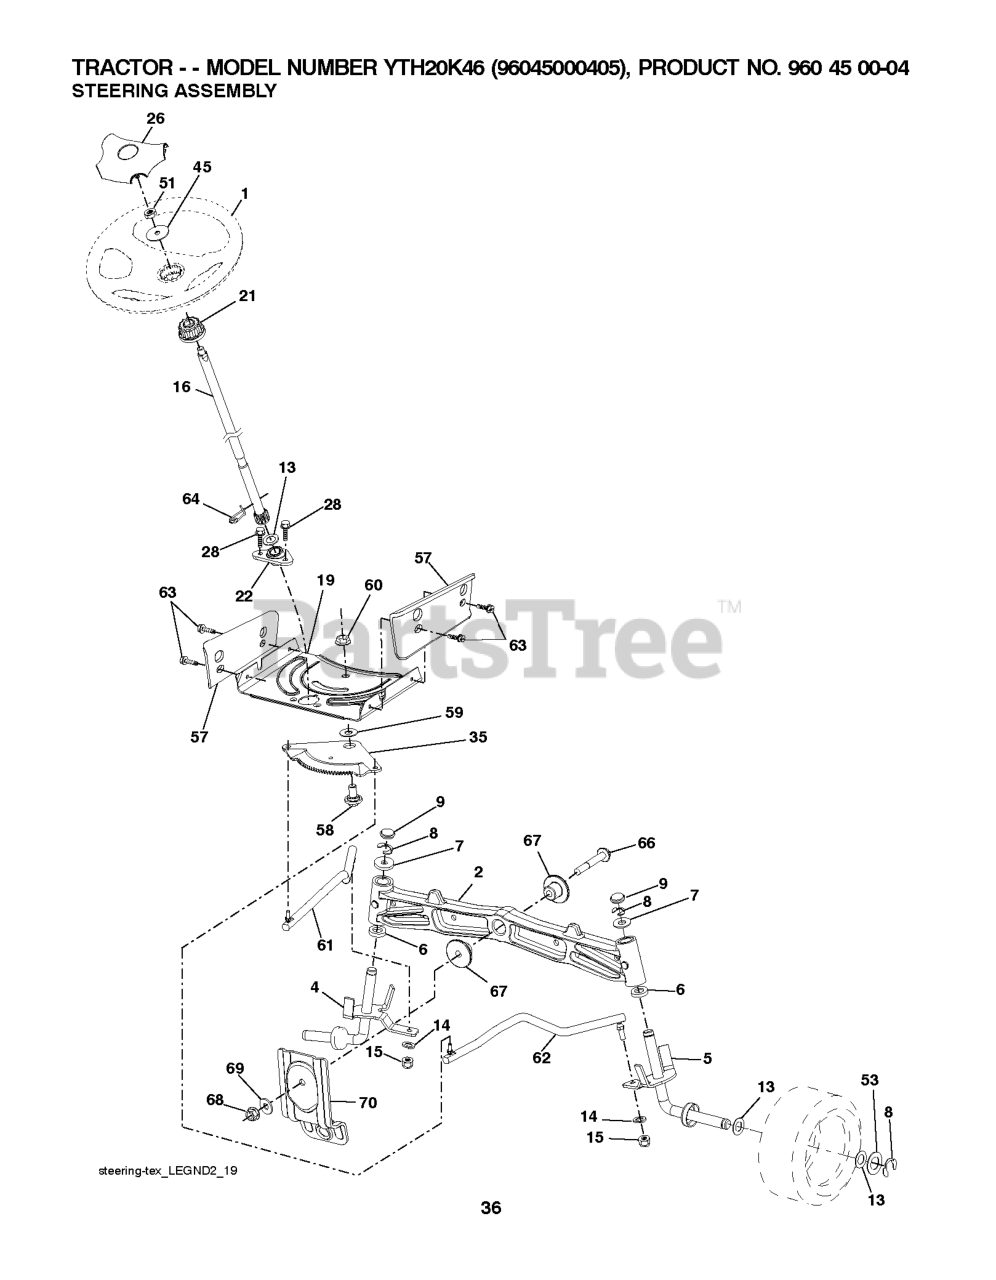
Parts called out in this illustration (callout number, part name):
1	WHEEL.STEERING.LEGEND2.GRY
2	AXLE ASSY FRONT
4	SPINDLE.WELDED.LH.15"TEX
5	SPINDLE.WELDED.RH.15"T
6	THRUST WASHER
9	CAP.SPINDLE.BLACK
14	WASHER, LOCK 3/8
15	NUT CROWNLOCK 3/8-24
16	SHAFT, STEERING
19	PLATE.STEER.DDL.NLT/NG
21	ADAPTER, WHEEL STNG..
22	BUSHING.ASM.STEERING.A
26	INSERT.CAP.STRG.WH.GRAY
28	SCREW, 3/8-16X3/4
35	GEAR.SECTOR.PLATE.DDL.
45	WASHER 9/16"ID, 2 3/8"OD
51	NUT.HEX.1/2-20
53	WASHER.HARDENED
57	BRACKET.UPSTOP.TEX
58	BOLT.SHOULDER.SECTOR.P
59	WASHER.THURST.SECTOR.S
60	NUT FLANGE LOCK 5/8-11
61	DRAGLINK.LH.BALLSTUD.D
62	DRAGLINK.RH.BALLSTUD.D
63	SCREW
64	RETAINER.CLIP.SPRING.S
66	BOLT HEX FGHD 7/16-14 X 3 SERR
67	BUSHING.PM.FRONT AXLE
68	NUT.LOCK.FLANGE.7/16
69	WASHER.1.5X.505X.118
70	BRKT.DECK.SUSPENSION.F
74	BRNG T
